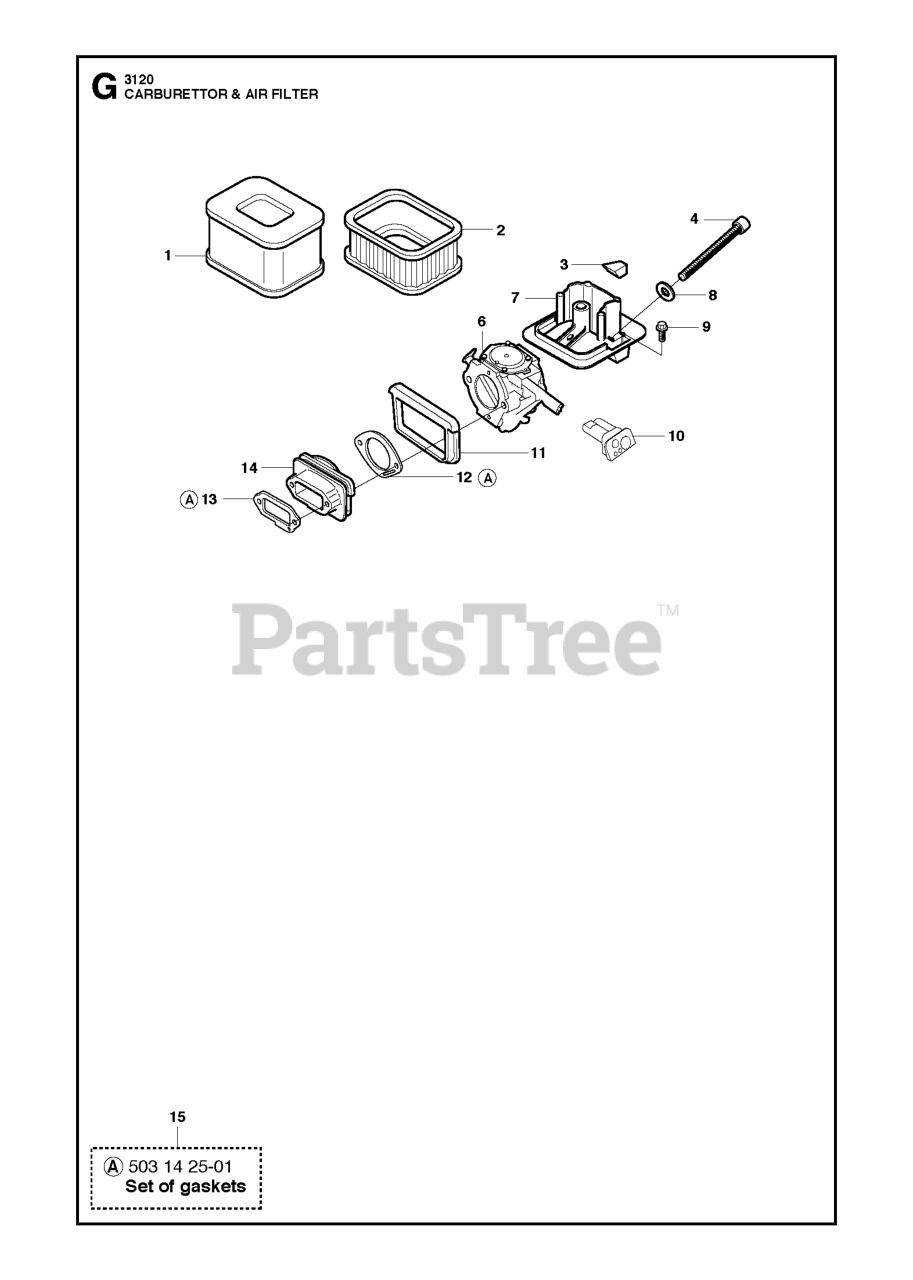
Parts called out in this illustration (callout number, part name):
1	AIRFILTER
2	AIR FILTER - FELT
6	CARBURETOR
6	CARBURETOR WG7 EPA
7	FILTER HOLDER
8	WASHER
15	GASKET SET
